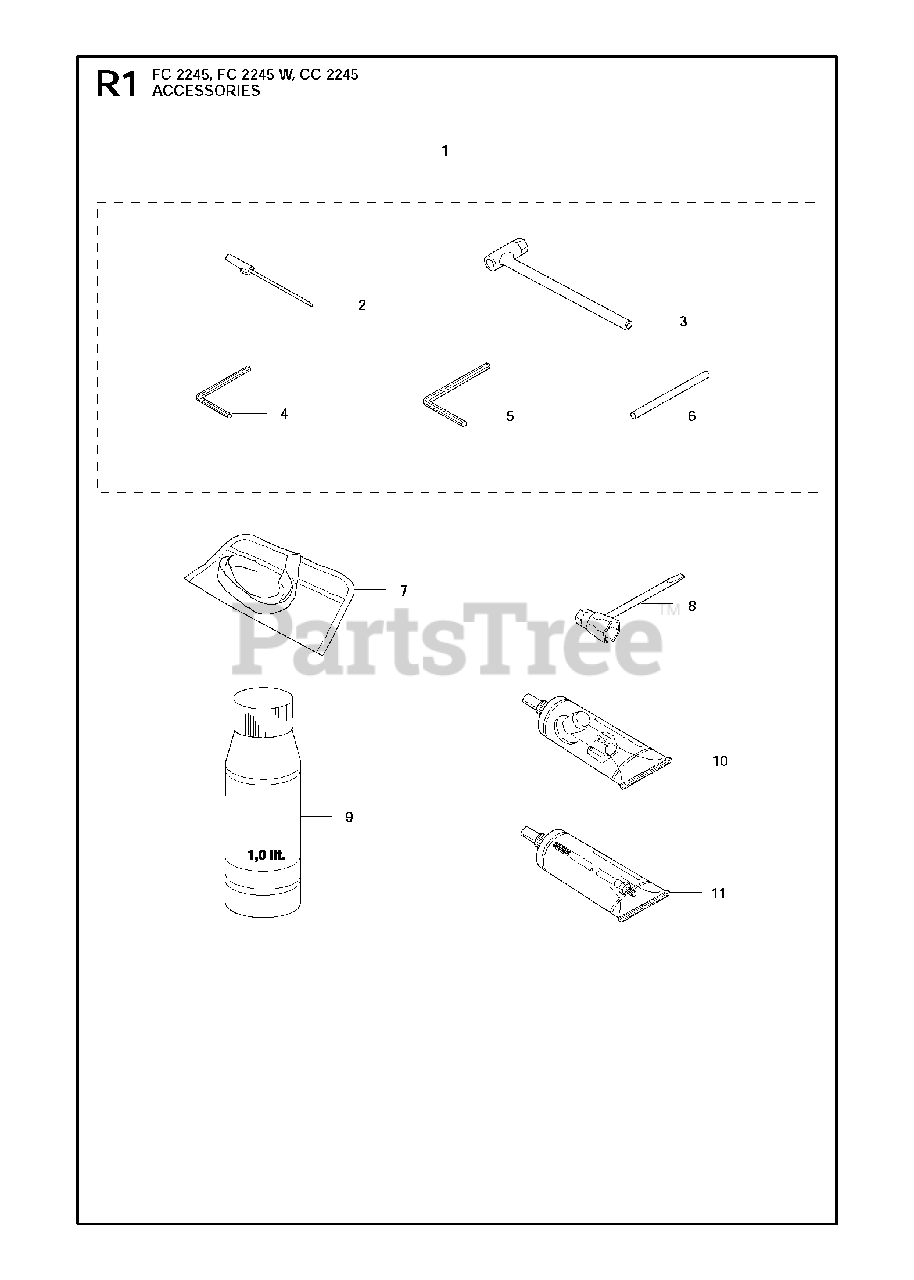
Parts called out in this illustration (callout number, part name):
1	TOOL KIT
2	SCREWDRIVER
3	SCRENCH
4	L-KEY WRENCH
5	L-SPANNER
6	LOCKING PIN
8	RP COMBI TOOL
9	AIR FILTER OIL
10	BEVEL GEAR GREASE
